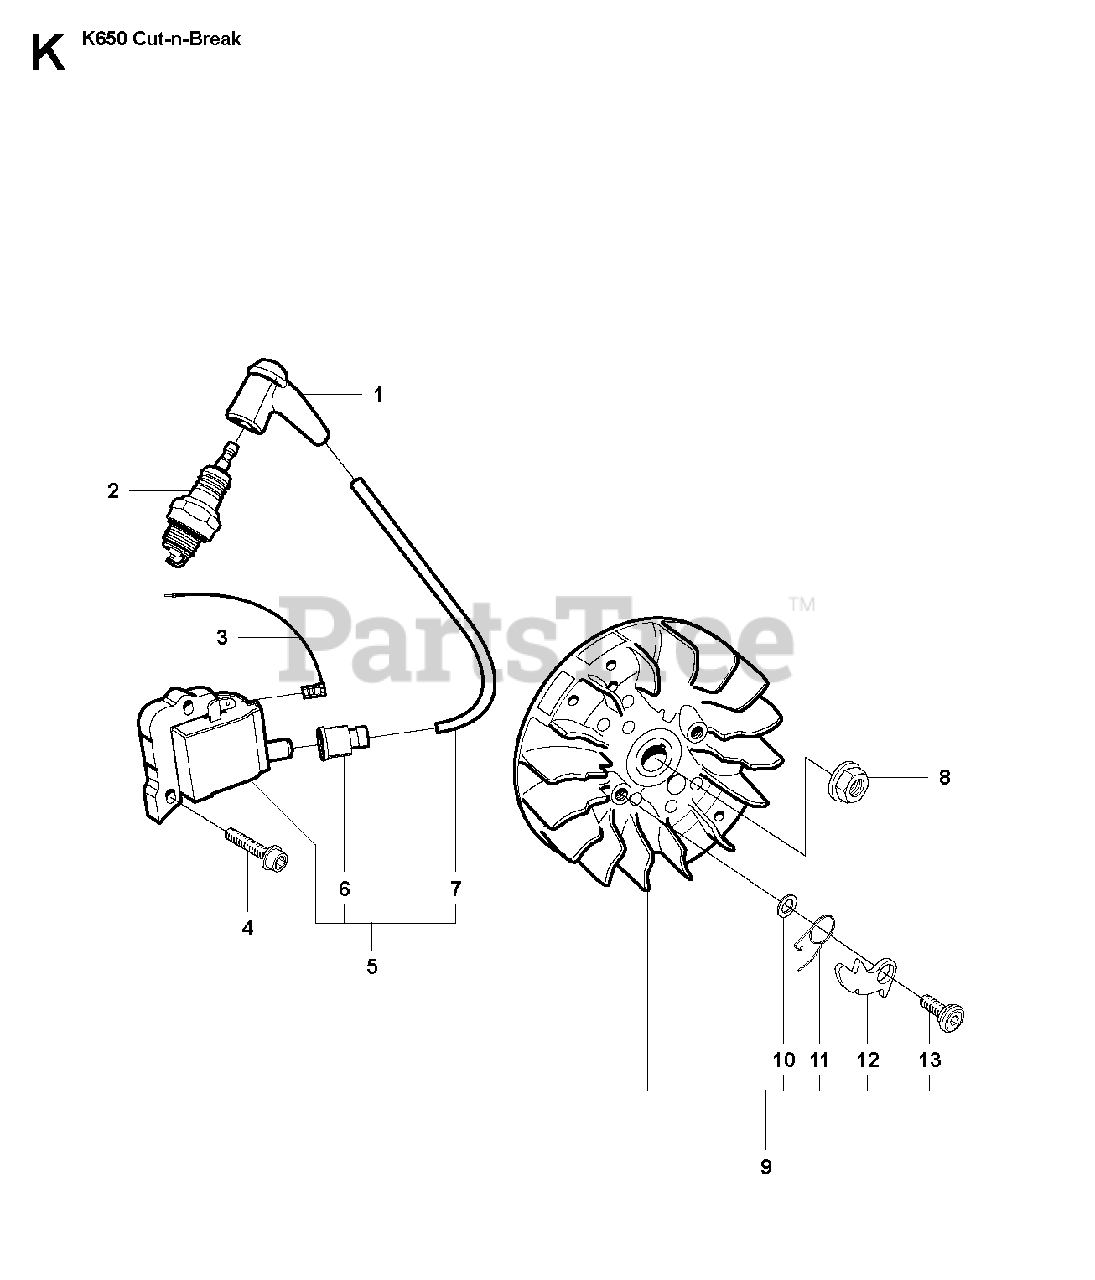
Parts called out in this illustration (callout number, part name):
1	SPARK PLUG CAP
5	IGNITION SYSTEMIncl. 6, 7
7	IGNITION CABLE340mm
9	FLYWHEEL ASSYIncl. 10 - 13
